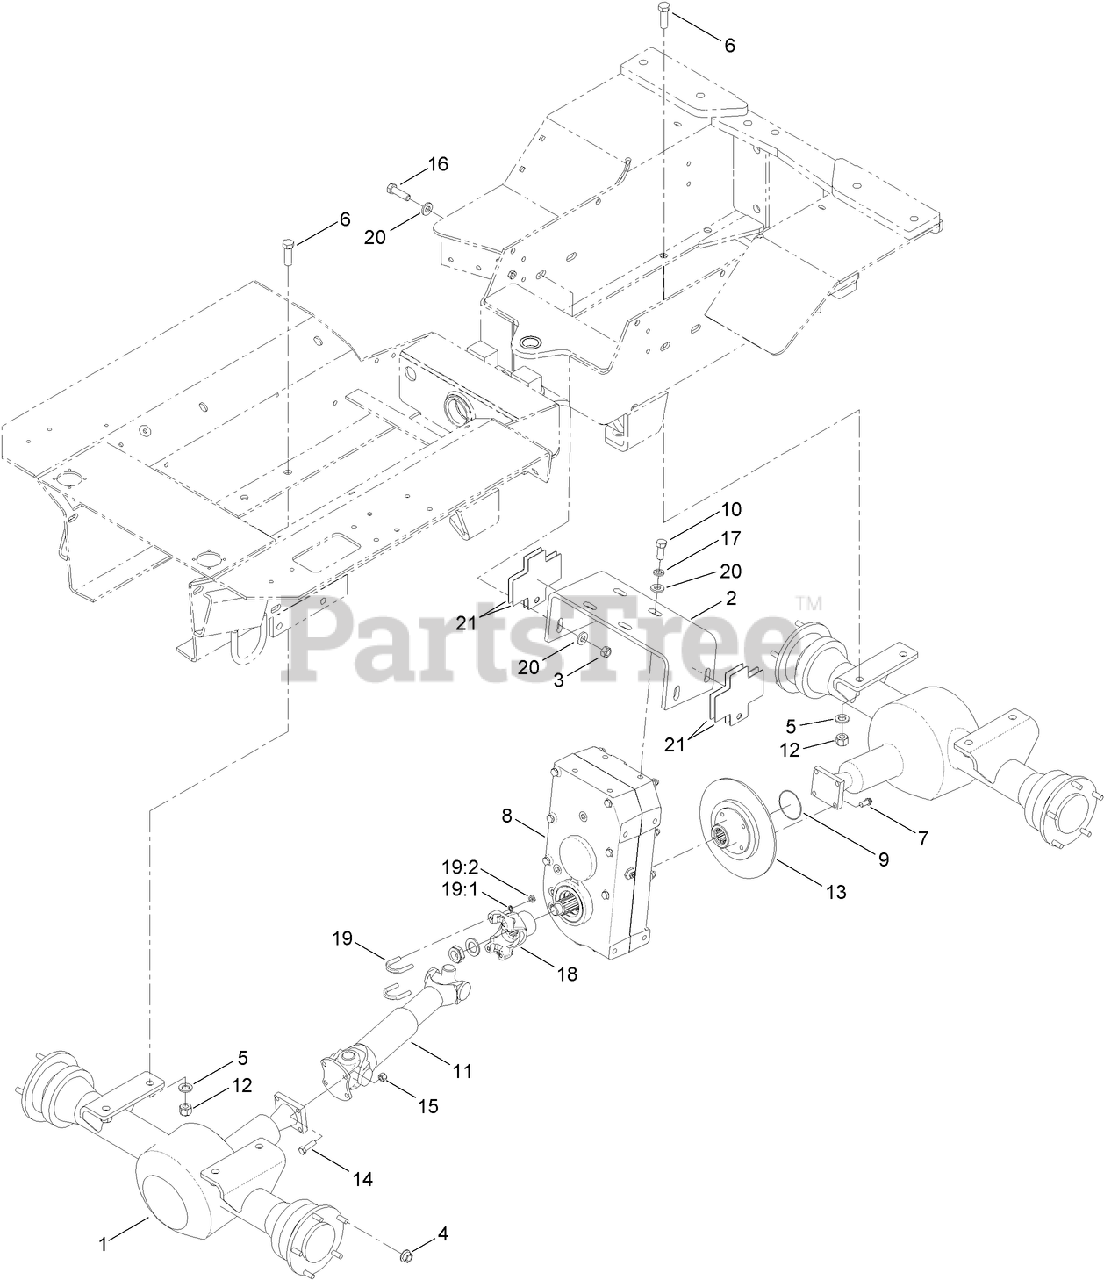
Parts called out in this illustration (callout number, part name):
1	AXLE-DRIVE
2	BRACKET-MOUNTING
3	LOCKNUT
5	WASHER-FLAT
7	SCREW-12 PT FLANGE
8	TRANSMISSION ASM
9	O-RING, SAE
10	SCREW-HH
11	DRIVE SHAFT ASM
13	FLANGE-COMPANION
14	SCREW-HH
15	NUT-HEX
16	SCREW-HH
17	WASHER-LOCK
18	YOKE-TRANSMISSION
19	BOLT-U (2 PER PACK)
19:1	NUT-HEX
19:2	WASHER-LOCK
21	Shim-Bracket
